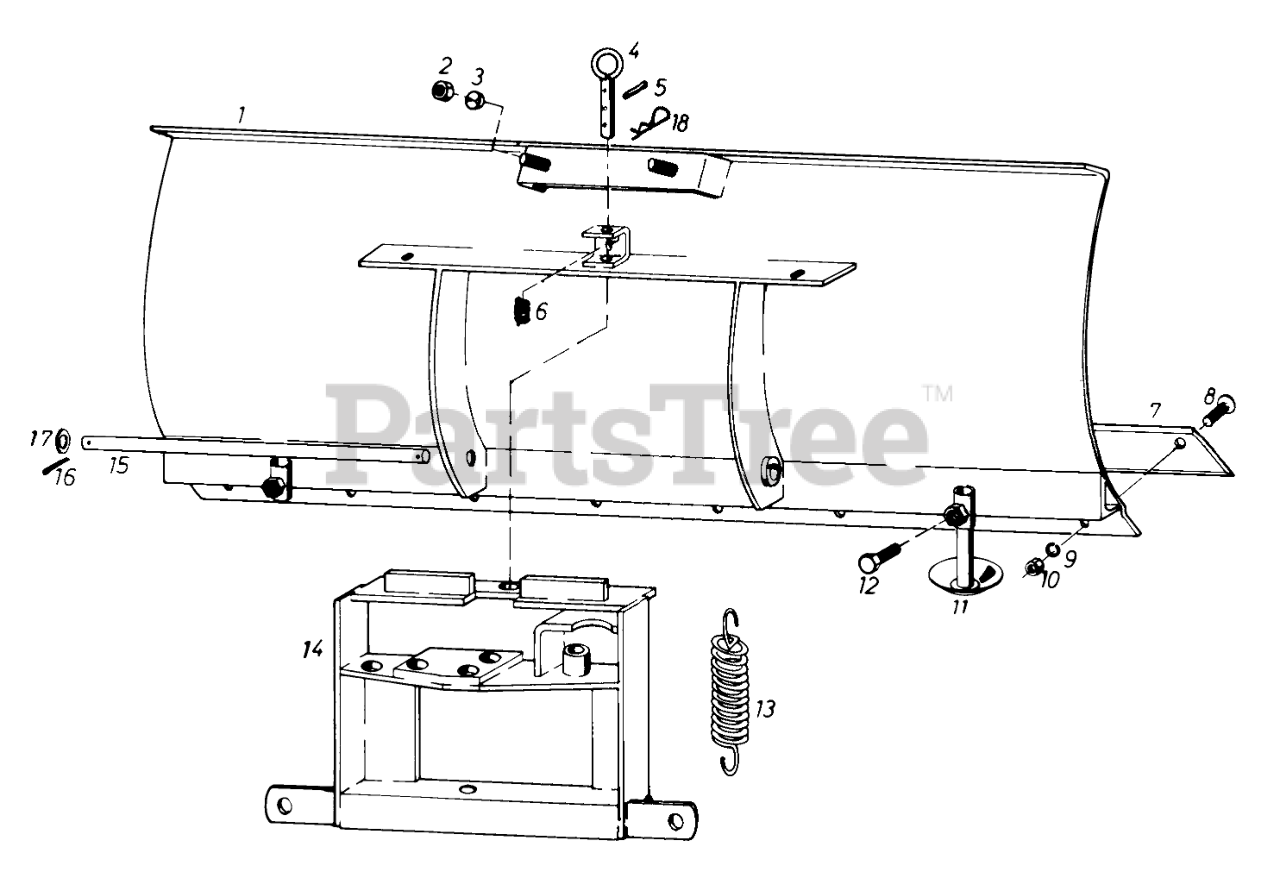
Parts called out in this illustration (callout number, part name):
1	Blade
3	Spring Lockasher
4	Trip Spring Lockout Pin
5	Rollpin
6	Spring
7	Scraper Blade
9	Lockwasher
13	Trip Spring
14	Indexing Bracket
15	Mounting Rod
17	Washer
18	Hairpin Cotter
